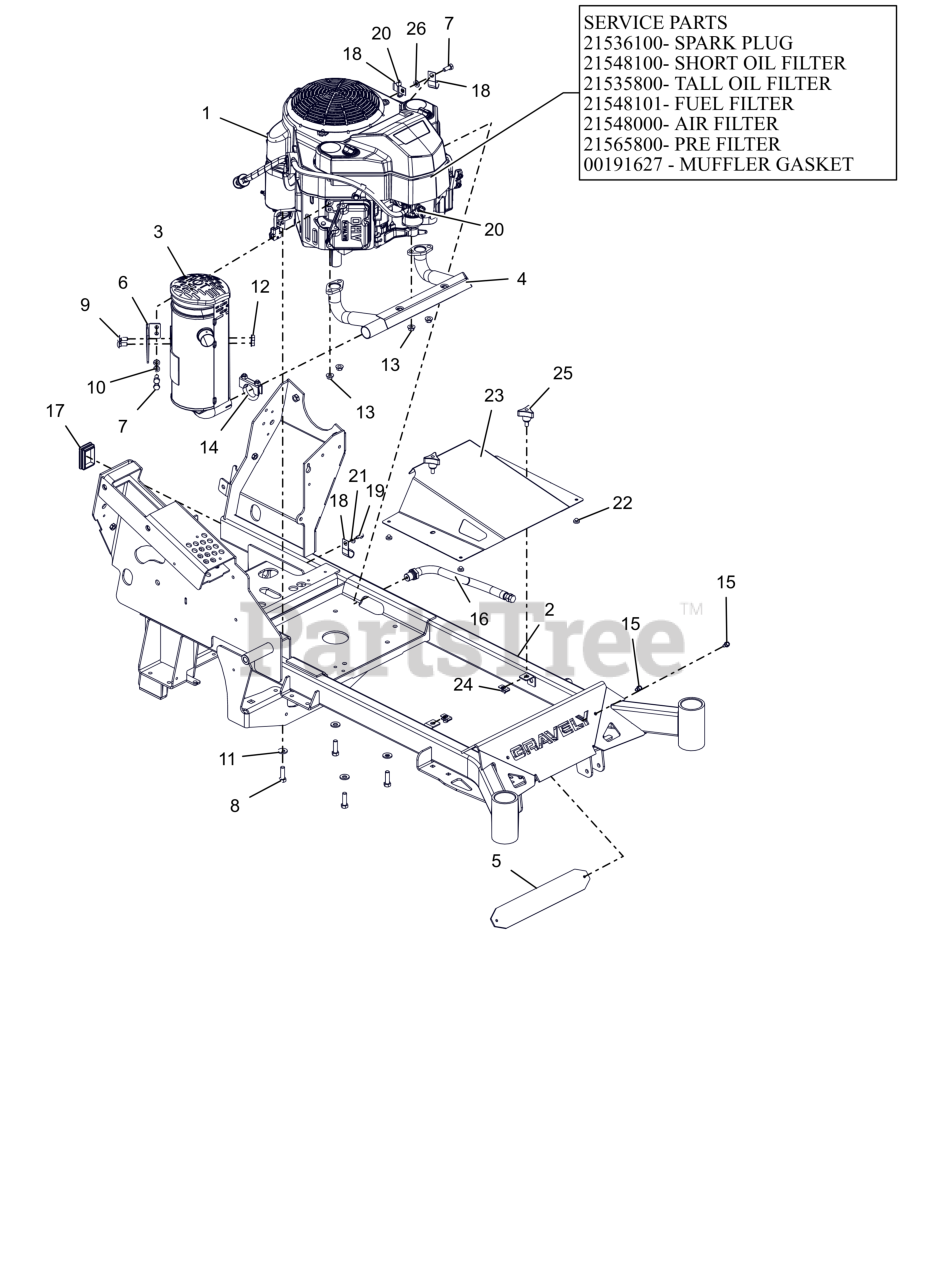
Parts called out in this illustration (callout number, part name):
1	ENG. KAW FS600
1	PLUG, SPARK
1	OIL FILTER, KAWASAKI FR
1	FILTER,OIL - KAW
1	FUEL FILTER-KAWASAKI FR
1	AIR FILTER, KAWASAKI FR
1	PRE FILTER, KAWASAKI FS
1	GASKET, MUFFLER S/O
2	WLDMT, PRO STANCE 36" FRAME
3	MUFFLER, PROSTANCE
4	MANIFOLD PRO STANCE 32-36" EXHAUST
5	BACK, NAMEPLATE
6	BRKT, MUFFLER MOUNT - FT730
7	BLT, HEX M8-1.25X20 G8.8 ZCC
8	BLT, HEX .38-16X1.25 G5 ZCC NT
9	BLT,RHSN .31-18X.75 G5 ZCC
10	WSHR,LK-REG .312X.078 ZCC
11	WASHER, 3/8" SPRING DISC
12	NUT,LK-CTR-FLG .31-18 GF ZCC
13	NUT-LK-TOP-FLG M8 ZCC
14	CLAMP, MUFFLER - 1.438
15	SCR-TAP .25-20X.50 HWH ZCC
16	HOSE, OIL DRAIN
17	PLUG, RECT 1.575 x 2.362
19	SCR-TAP .25-20X.50 HWH ZCC
20	CABLE TIE, .15 X 8.50
21	WSHR,FLT .281X.625X.065 ZCC
22	BUMPER GROMMET
23	COVER, BELT (RED)
24	NUT-CLIP RETAINER 5/16-18X.56
25	KNOB,WING STUD 5/16-18 X .75
26	WSHR,FLT .344X.688X.065 ZCC
